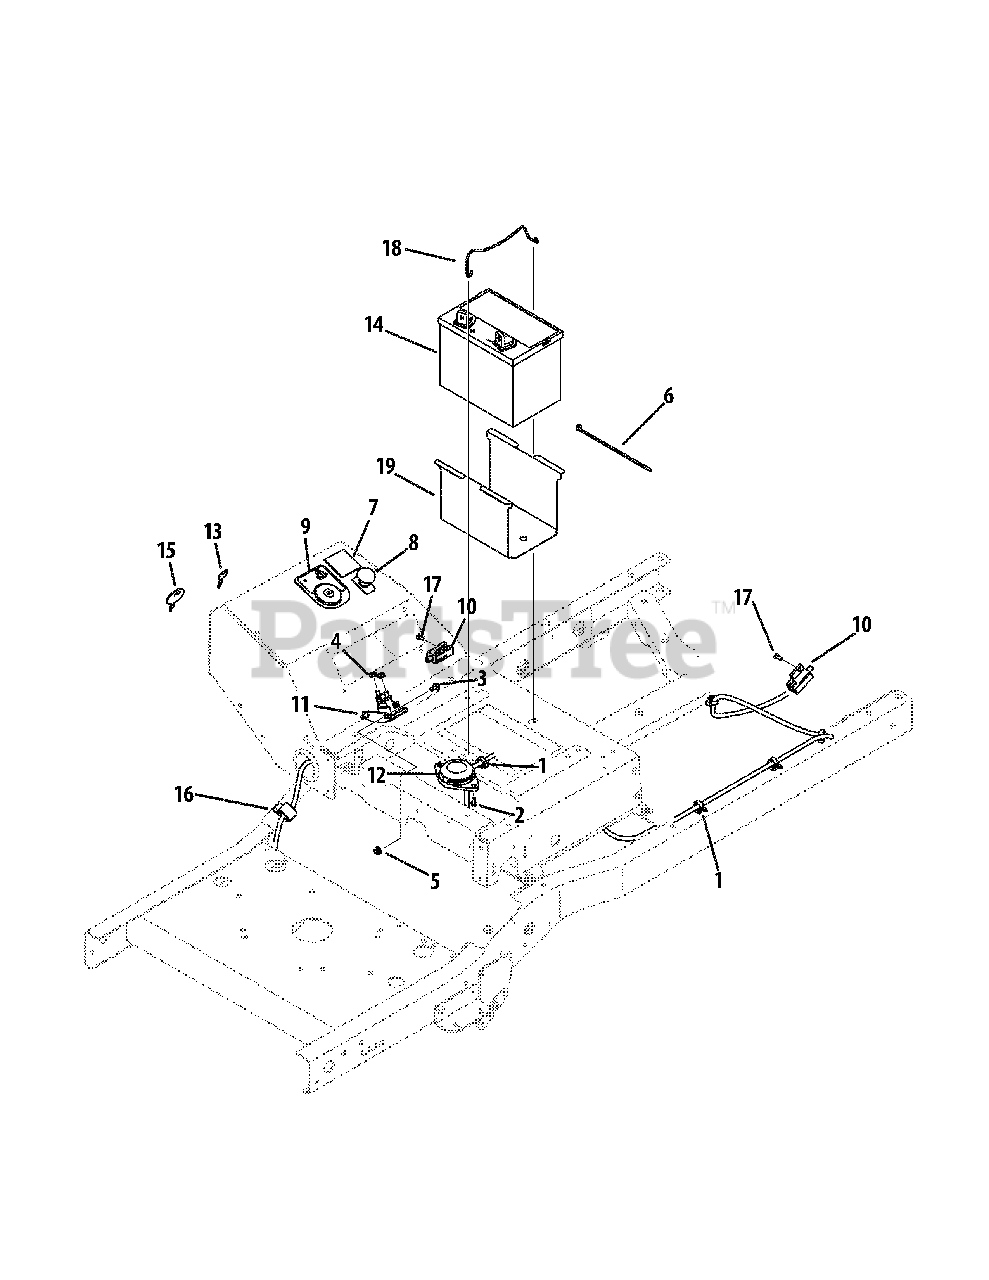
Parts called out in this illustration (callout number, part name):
1	Electrical Conduit Clip, 1/2
2	Hex Washer Screw, #12-16 x .50
3	Hex Washer Screw, 1/4-20 x 0.500
4	Sems Nut, 1/4-20
5	Flange Lock Nut, 1/4-20
6	Cable Tie, 3/16 x .05 x 7.4
7	Hour Meter/Service Minder
8	Electric PTO Switch
9	Key Switch
10	Interlock Switch
11	Solenoid
12	Seat Switch
13	Universal Key
15	Key
16	Clamp, 1.0
17	Shoulder Screw, #10-32 x .500
18	Battery Rod
